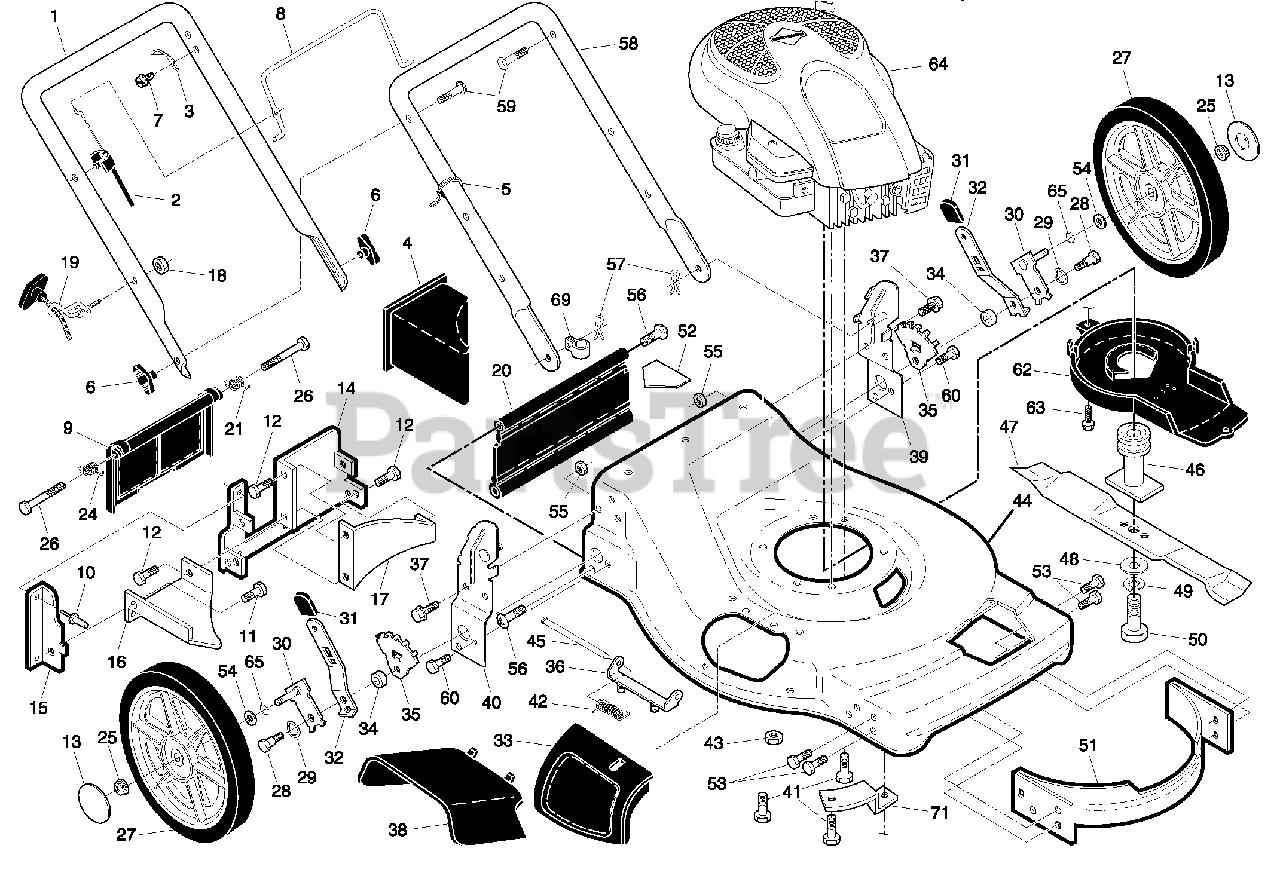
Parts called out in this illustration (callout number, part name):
1	Drive Control Assembly
6	Retainer, Spring
7	Bar, Drive Control
11	Wheel & Tire Assembly, Front
12	E-Ring
13	Pinion
14	Dust Cover
15	Pawl, Drive
16	Washer, Flat 3/8
17	Bearing, Wheel Adjuster
18	Selector Knob
27	Pan Head Tapping Screw #10-24 x 2-3/4
28	Drive Cover
29	Locknut, Hex
35	Kit, Wheel Adjuster, LH
36	Gear Case Assembly, Complete
38	Locknut 1/4-20
40	Spring
41	Kit, Wheel Adjuster, RH
54	Grassbag Assembly
56	Hubcap
57	Frame, Grassbag
60	Case, Lower
61	Case, Upper
62	Gear, 27 Teeth
63	Lever, Clutch
64	Spring, Return
65	Shaft, Input
66	Dog, Movable
67	Dog, Fixed
68	Wire, Formed
69	Bearing, Ball
70	Fork, Shift
71	Seal, Output Shaft
72	Washer
73	Seal, Case
74	Bushing
75	Shaft, Output
76	Screw
77	Seal, Input Shaft
78	Pulley, Drive
79	Locknut, Hex
